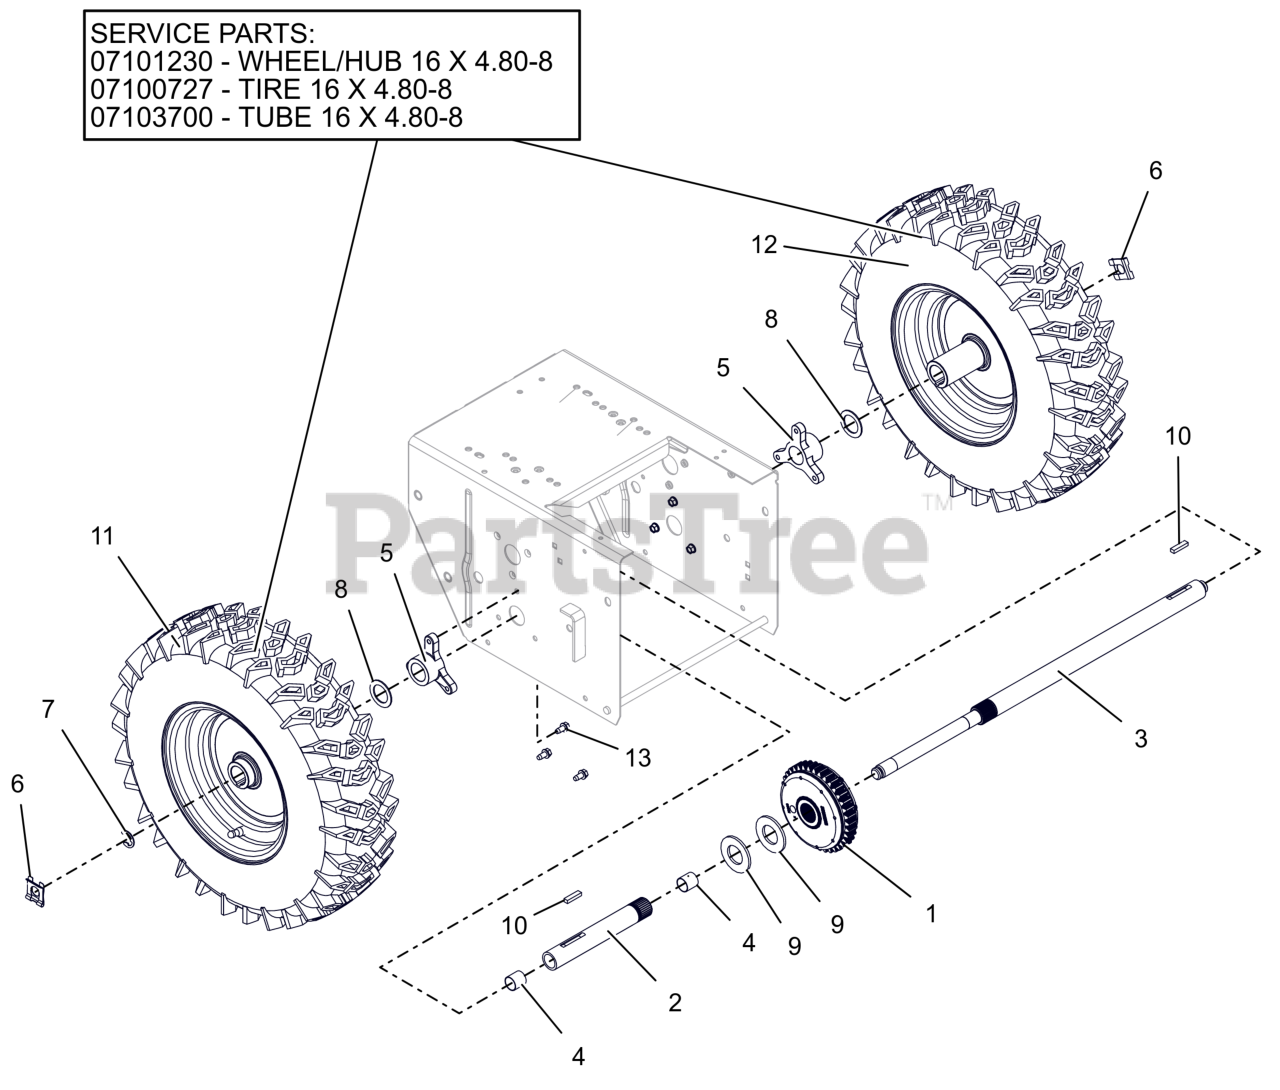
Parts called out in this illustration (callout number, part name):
1	DIFFERENTIAL, AUTOMATIC
2	AXLE, SHORT - W/BUSHINGS
3	AXLE,LONG-DELUXE AUTO DIFF
4	BSHG-SLV .706X.764X.75 BRZ
5	BUSHING, AXLE
6	CLIP, SNAP .625 DIA
7	RG-RTNG-EXT .625X.042
8	WSHR, FLT 1.010X1.505X.062 ZCC
9	WSHR, FLT 1.062X2.000X.134 ZCC
10	KEY-RECT .25X.188X1.00
11	TIRE/WHEEL,RH 16X4.8-8 DIFF T2
12	TIRE/WHEEL,LH 16X4.8-8 DIFF T2
13	SCR-TAP .25-20X.50 HWH ZCC
